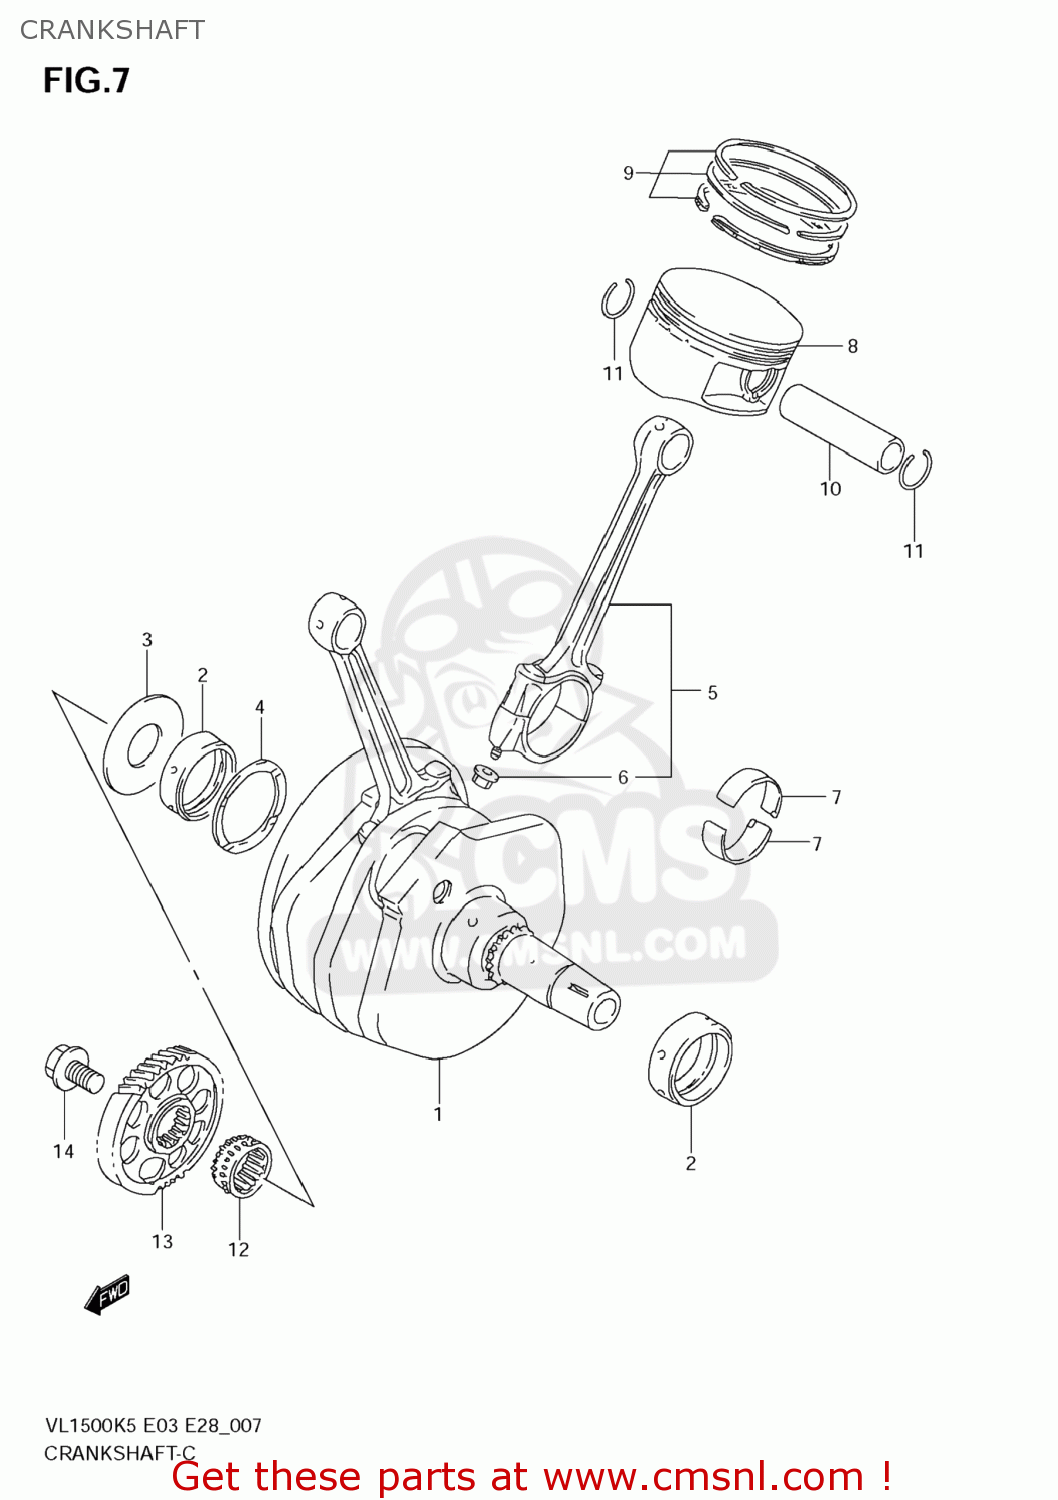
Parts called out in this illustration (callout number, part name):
1	CRANKSHAFT SET
2	METAL,CRANKSHAFT
3	WASHER,CRANK THRUST
4	PLATE,CRANK THRUST
5	CONNECTING ROD ASSY
6	NUT
7	METAL,CRANK PIN
8	PISTON
9	RING SET,PISTON
10	PIN,PISTON
11	CIRCLIP
12	SPROCKET,CAM CHAIN DRIVE,R
13	GEAR,PRIMARY DRIVE
14	BOLT(14X28)
